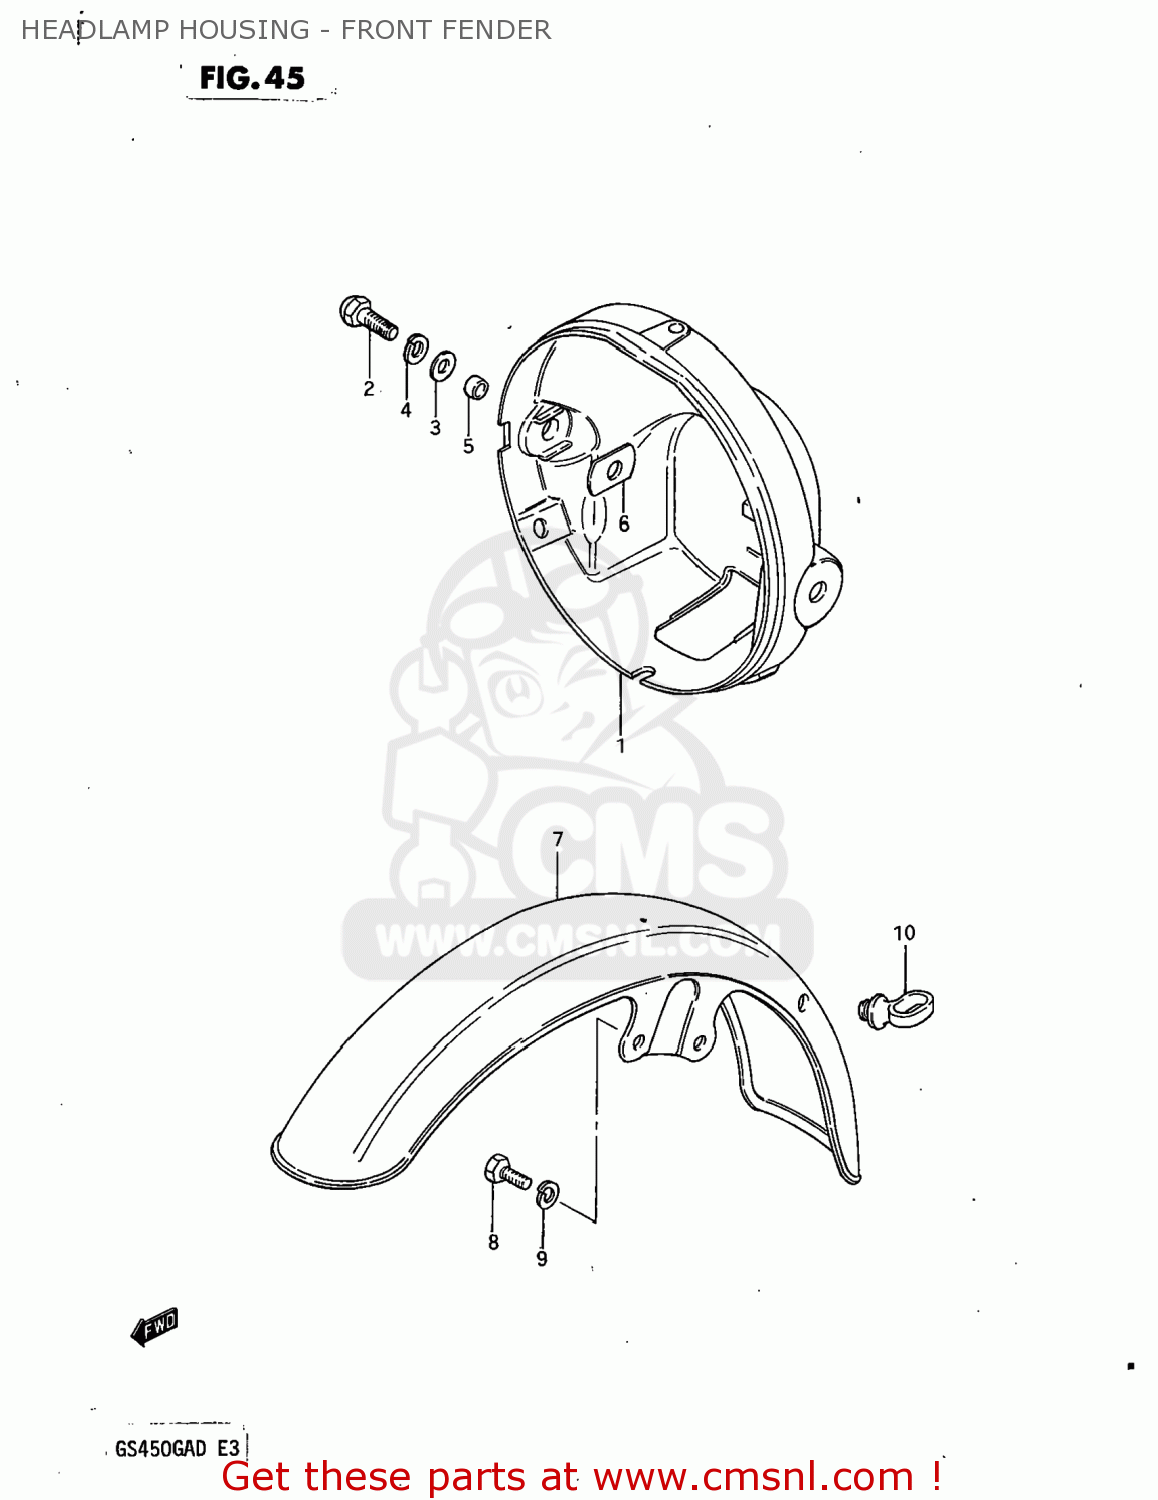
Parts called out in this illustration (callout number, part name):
1	HOUSING,HEADLAMP
2	BOLT
3	WASHER
4	LOCK WASHER
5	SPACER (8.8X12X7)
6	CUSHION
7	FENDER,FRONT
8	BOLT
9	LOCK WASHER
10	GUIDE,CABLE
